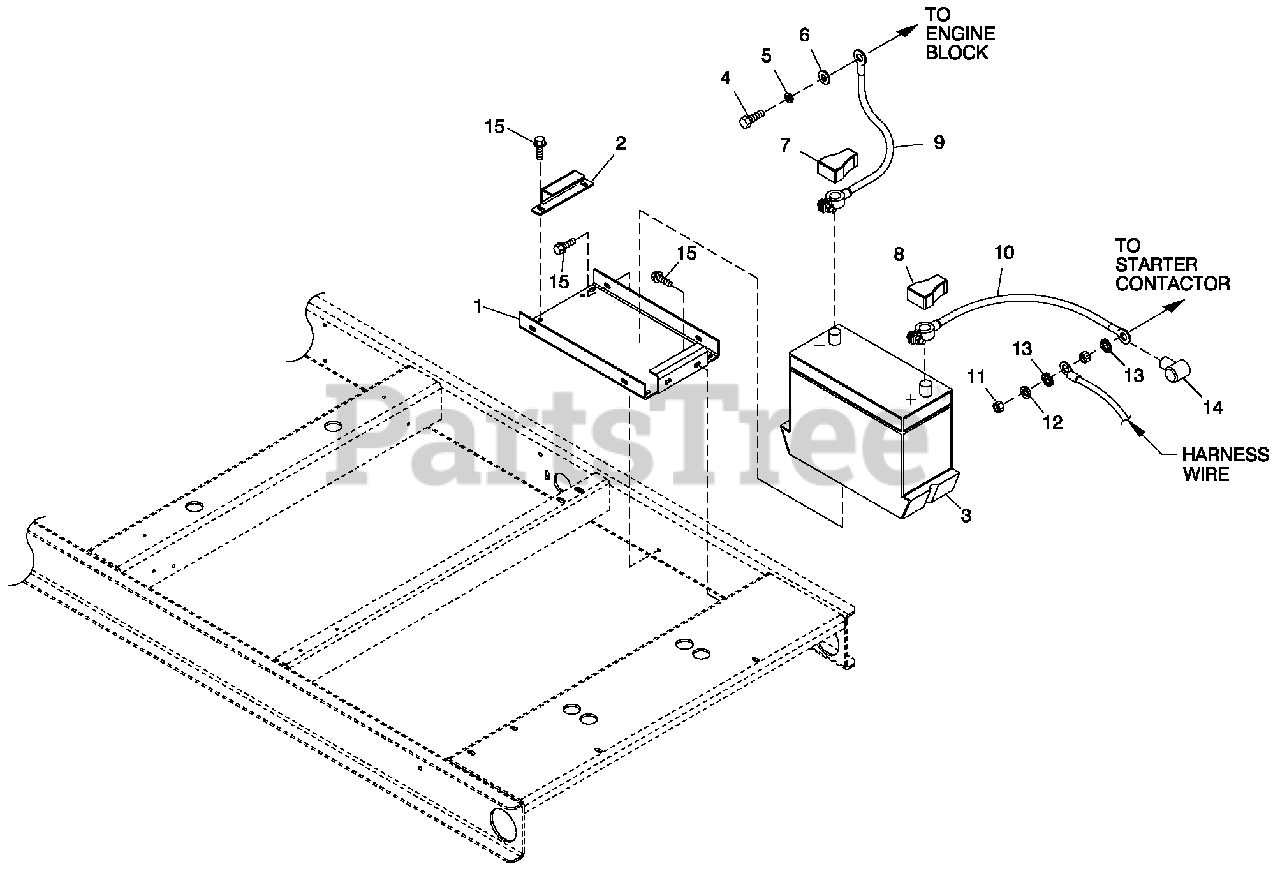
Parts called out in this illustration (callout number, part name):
1	TRAY BATTERY
2	STRAP BATTERY RETAINMENT
3	BATT 12VDC 24F 625
4	SCREW HHC 3/8-16 X 1 G8
5	WASHER LOCK 3/8
6	WASHER FLAT 3/8-M10 ZINC
7	BATT POST COVER RED +
8	BATT POST COVER BLK -
9	CABLE BATT BLK #1 X 23.00
10	CABLE BATT RED #1 X 35.00
11	NUT HEX M 8-1.25 G8 YEL CHR
12	WASHER LOCK M8-5/16
13	WASHER SHAKEPROOF EXT 5/16 STL
14	BOOT BATTERY CABLE
15	SCREW THF M6-1 X 16 N WA Z/JS
